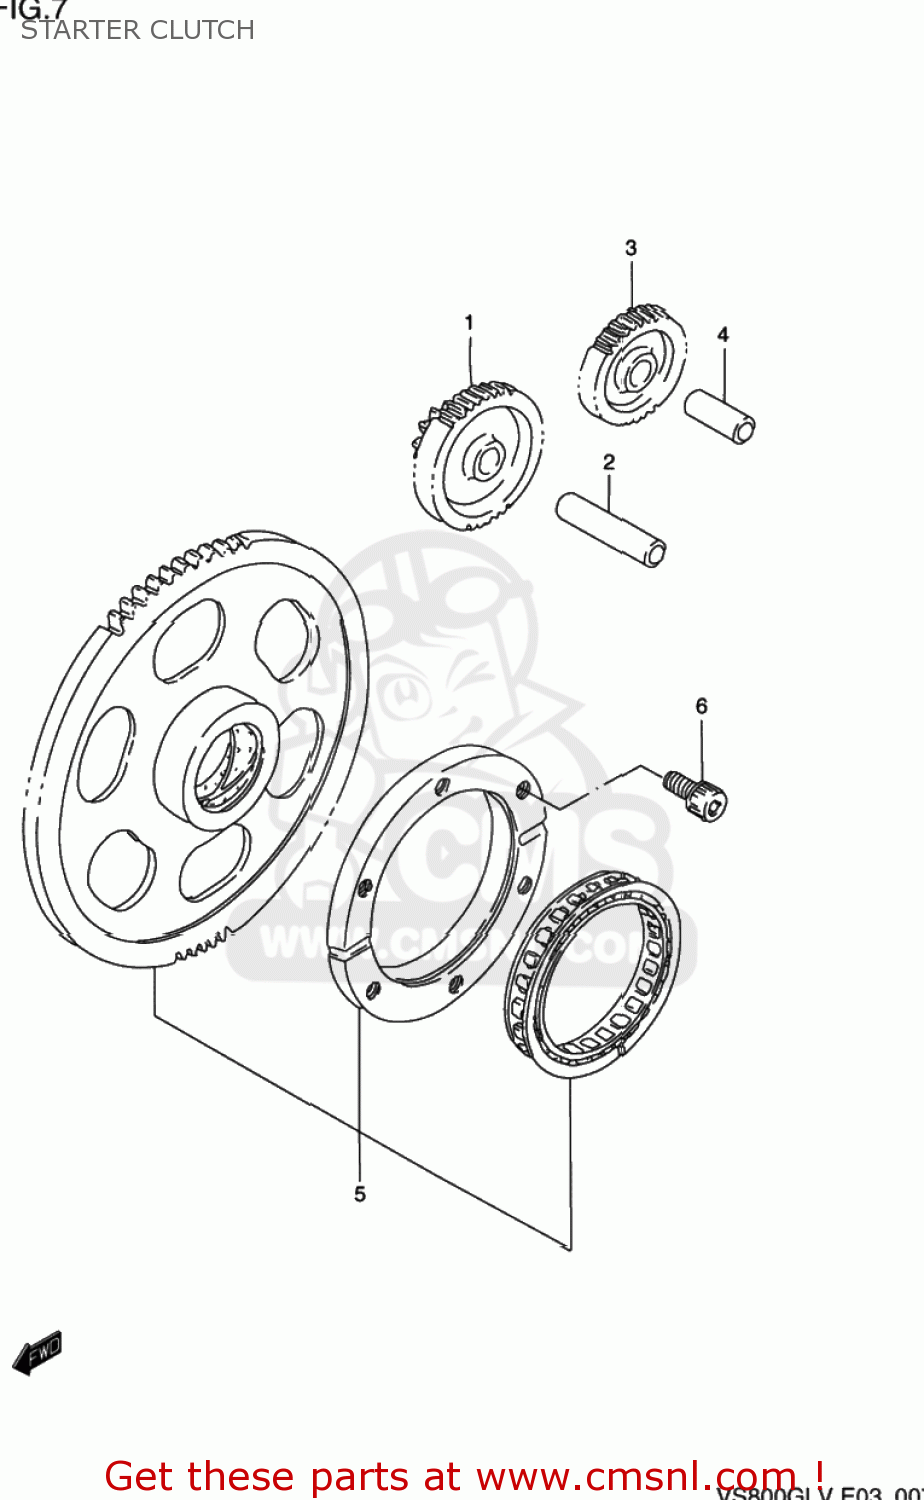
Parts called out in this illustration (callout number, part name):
1	GEAR,STARTER IDLE NO.1
2	PIN
3	GEAR,STARTER IDLE NO.2
4	PIN
5	CLUTCH SET,STARTER
6	BOLT
